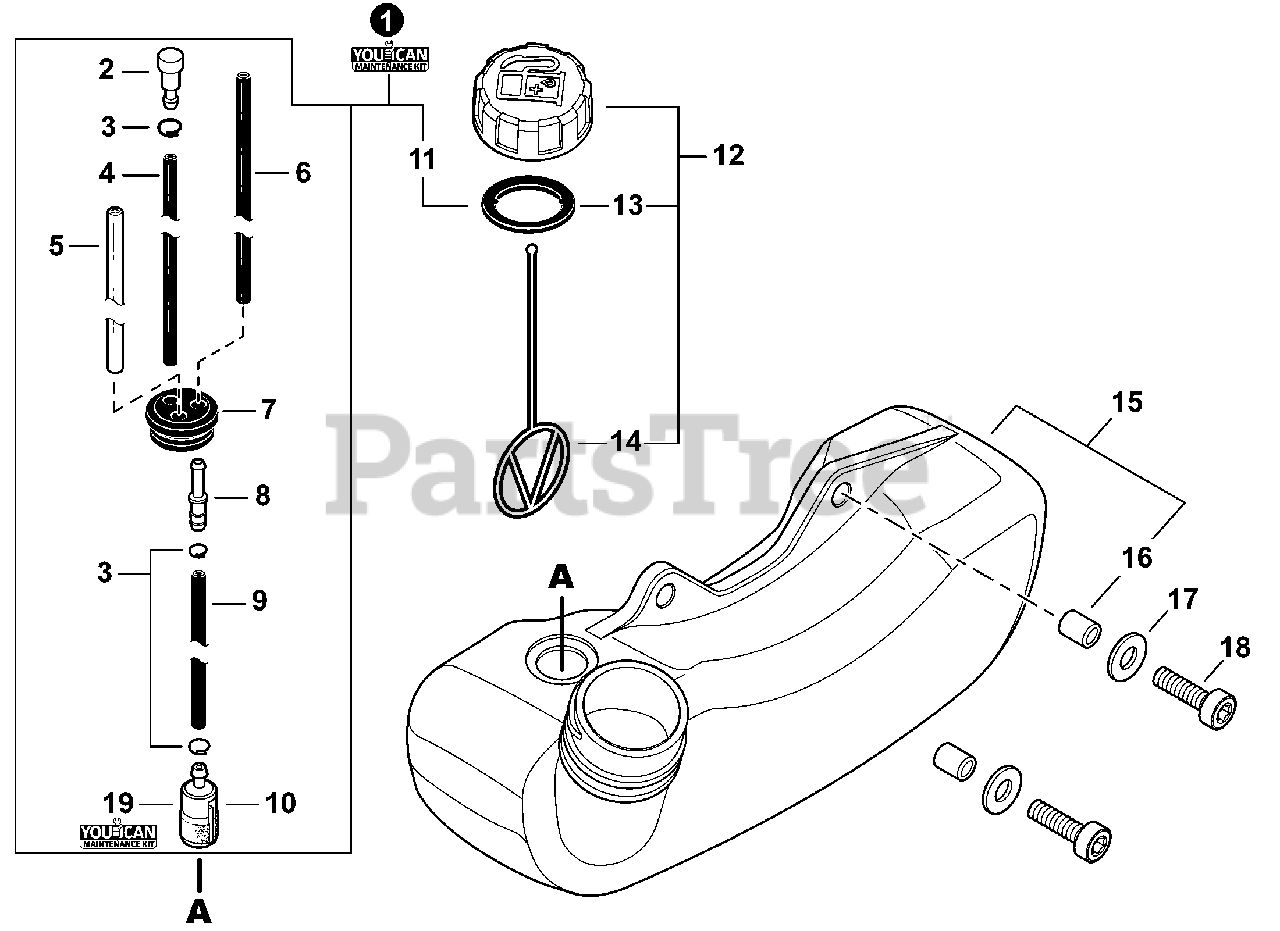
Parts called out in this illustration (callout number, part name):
1	FUEL SYSTEM KIT - YOUCANT
2	VENT ASSY
3	CLIP Ø6
4	PIPE, FUEL 3×5×80 BLACK
5	PIPE, FUEL 3×6×85 CLEAR
6	PIPE, FUEL 3×5×78 BLACK
7	GROMMET, FUEL Ø5
8	CONNECTOR, PIPE Ø5ר3.5
9	PIPE, FUEL 3×5×130 BLACK
10	FILTER, FUEL
11	GASKET, FUEL CAP
12	CAP ASSY, FUEL
13	GASKET, FUEL CAP
14	CONNECTOR, CAP L= 100 MM
15	TANK ASSY, FUEL
16	SPACER 6.2×7.8×6
17	WASHER 5.5×12×0.8
18	BOLT, TORX 5×16
19	TUNE-UP KIT - YOUCANT
